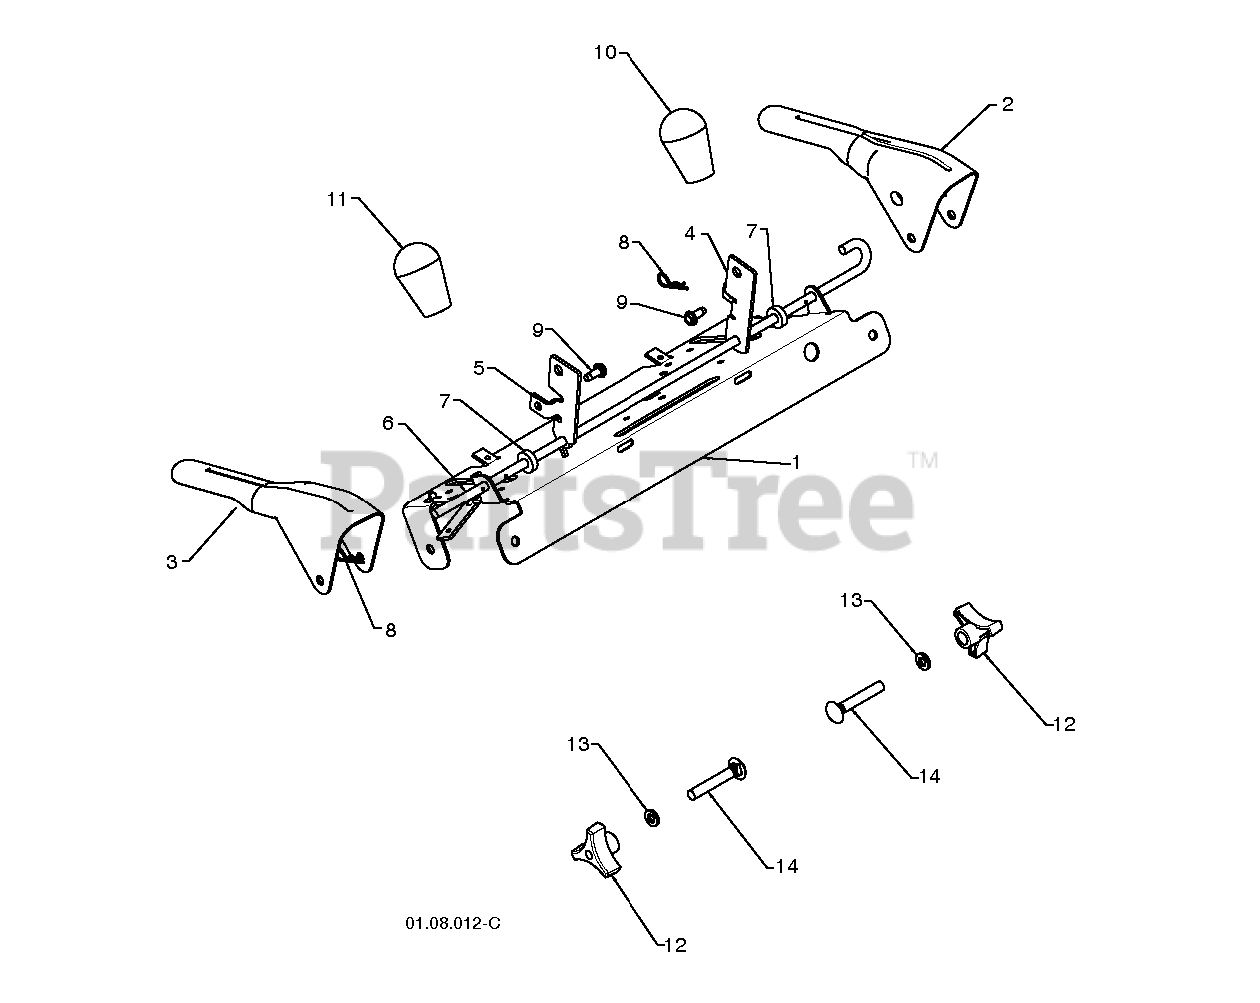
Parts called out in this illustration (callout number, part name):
1	PANEL.CONTROL
2	LEVER.CONTROL.LH.BLACK
3	LEVER.CONTROL.RH.GREY
4	ARM.TRACTION.ROD.YZ
5	ARM.IMPELLER.ROD.SNOW
6	BAIL.CONTROL.INTERLOCK
7	SPACER.CONTROL.LEVER
8	SPRING RETAINER
9	SCREW 14-20 X 5/8
10	KNOB LEVER, BLACK
11	RED KNOB SHIFTER
12	KNOB.HANDLE.3/8.TRI-POINT.BLAC
13	WASHER
14	BOLT 3/8-16 X 2-1/4
